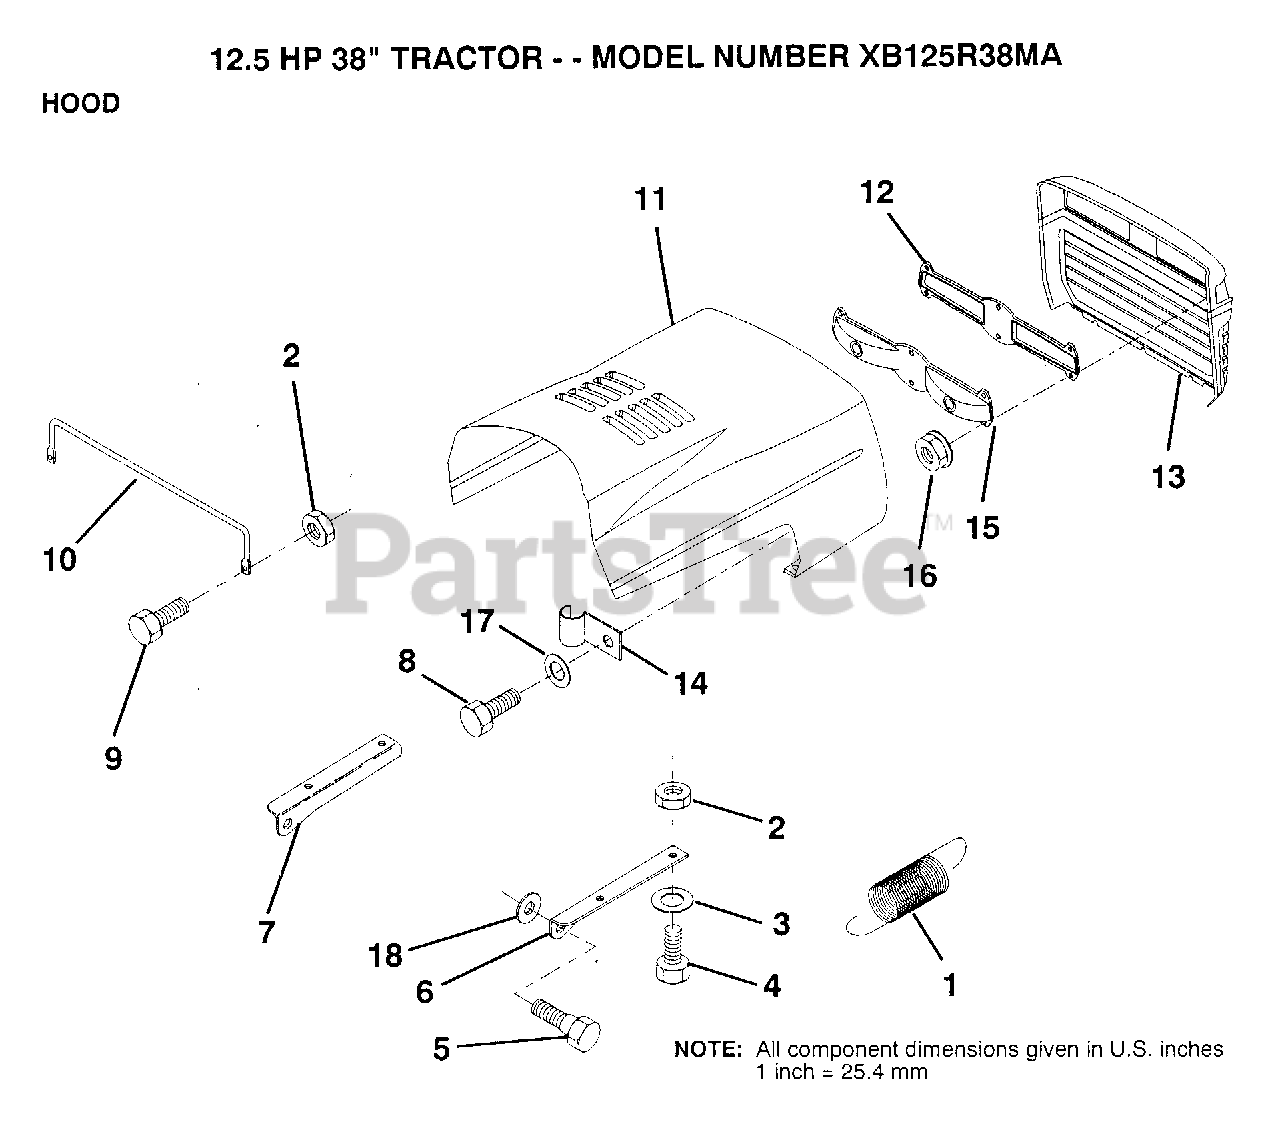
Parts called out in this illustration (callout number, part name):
1	EXT SPRING
2	NUT
3	WASHER
4	BOLT
6	BRKT HOOD RH
7	BRKT HOOD LH
10	"BRACE,HOOD"
13	GRILL (BLACK)
14	CLIP T
16	NUT
17	WASHER PM
18	WASHER
